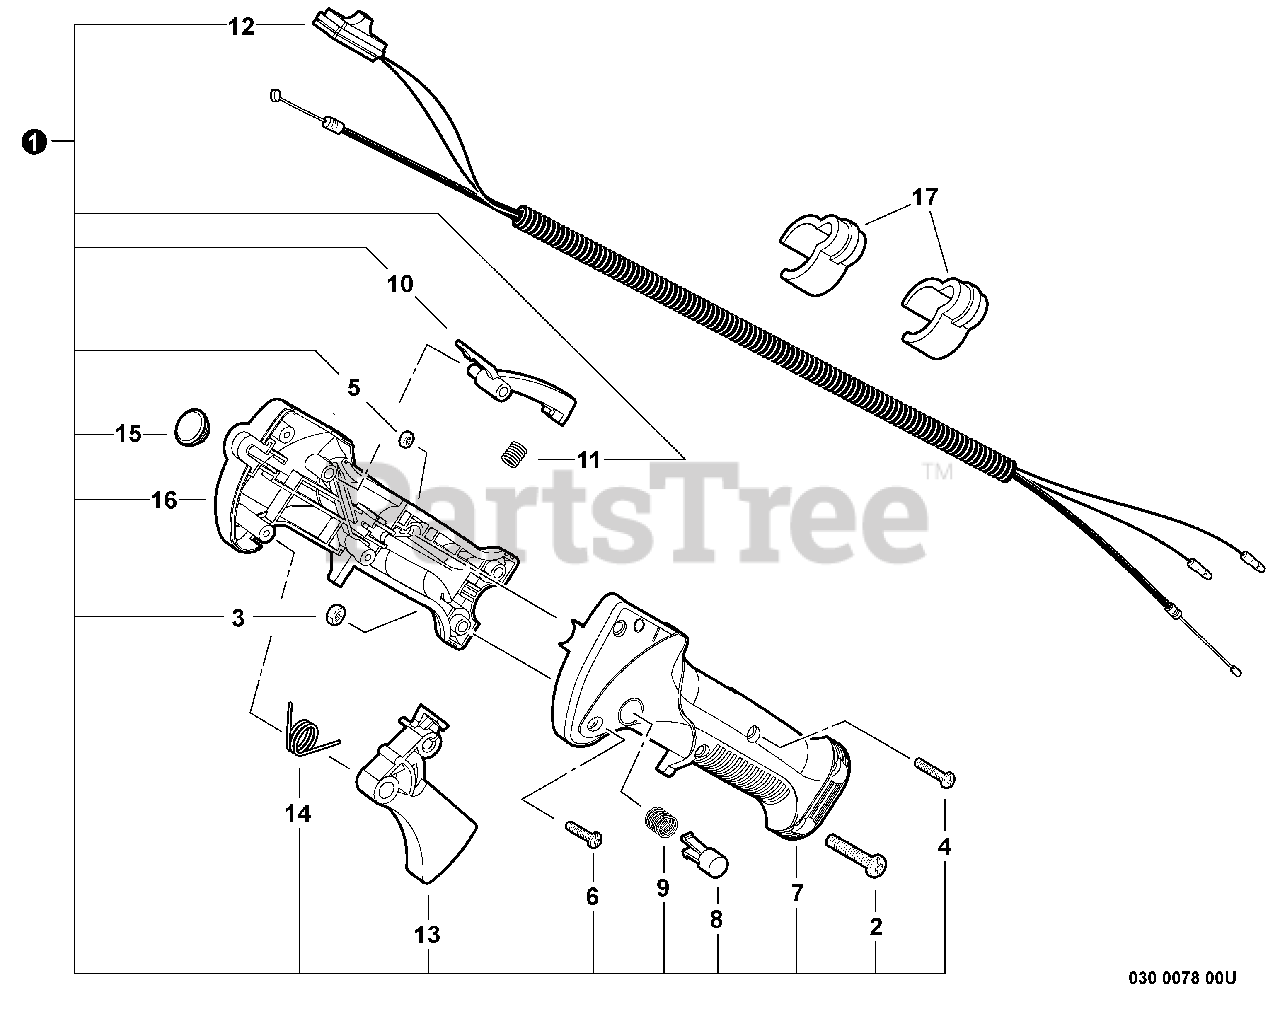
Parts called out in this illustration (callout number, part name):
1	THROTTLE CONTROL ASSY
2	SCREW M5×20
4	SCREW M4×23
6	SCREW, TAPPING 4×16
7	CONTROL HANDLE - LEFT
8	BUTTON, THROTTLE LOCK
9	SPRING, COMPRESSION
10	LOCKOUT, THROTTLE
11	SPRING, COMPRESSION
12	CABLE ASSY, CONTROL
13	TRIGGER, THROTTLE
14	SPRING, TORSION
15	PLUG, RUBBER
16	CONTROL HANDLE - RIGHT
17	CLIP, CABLE 25 MM
